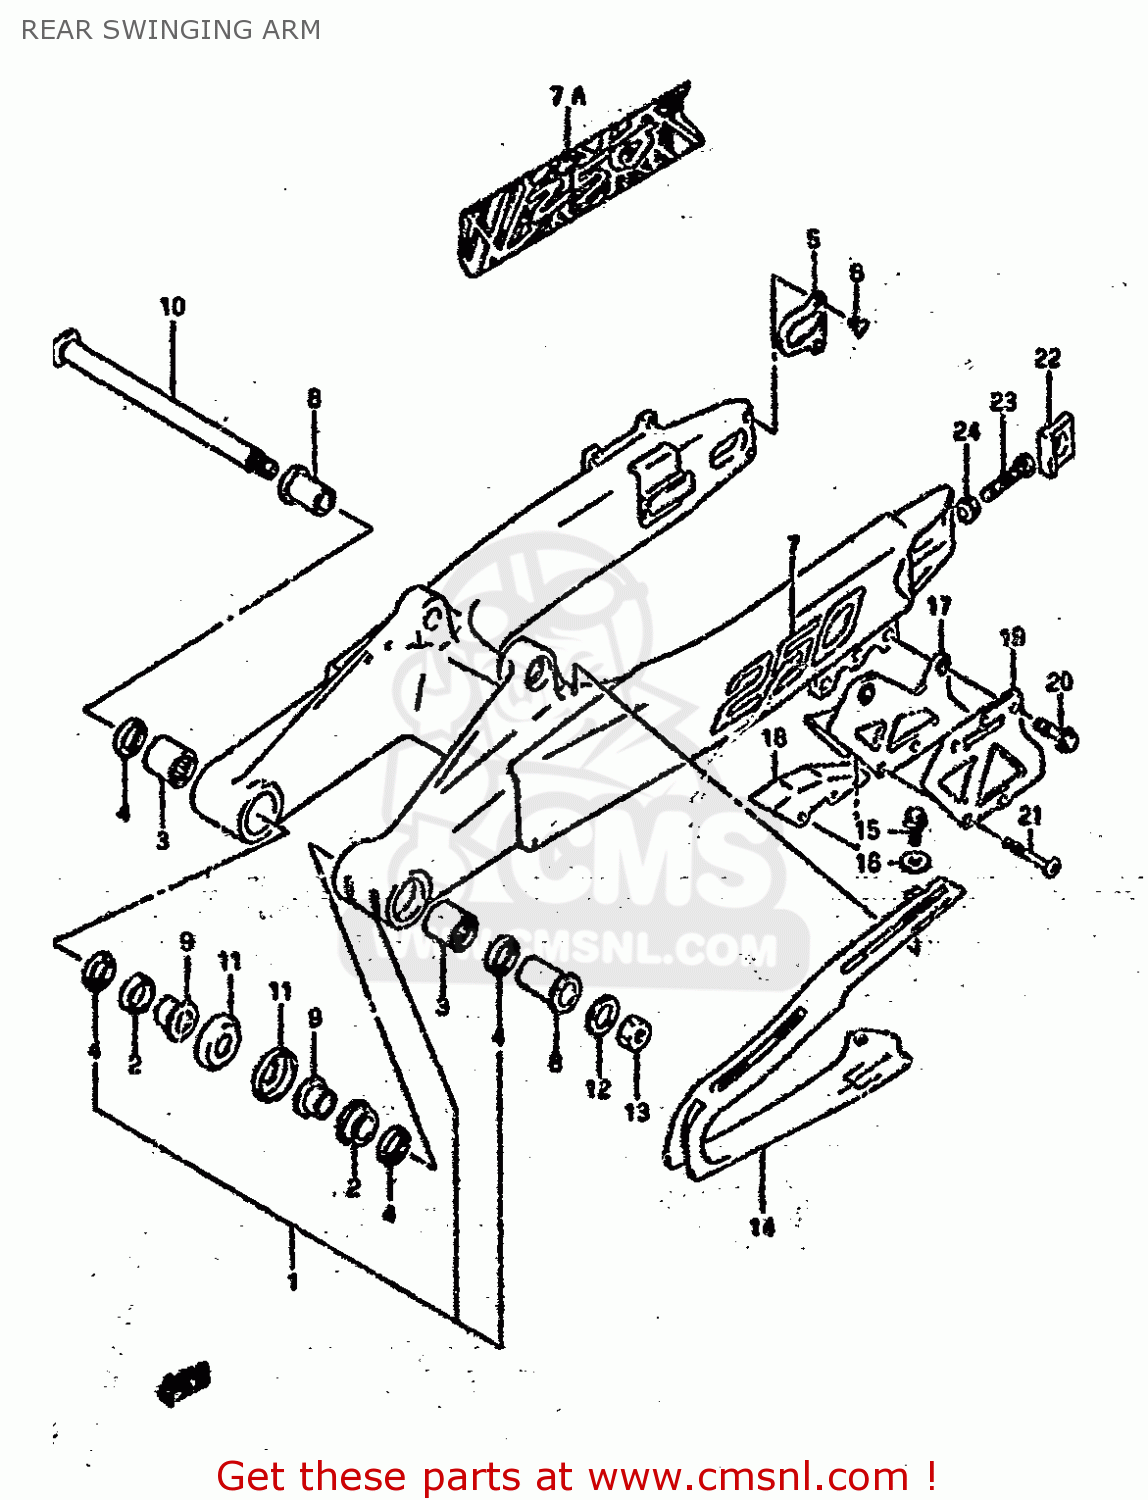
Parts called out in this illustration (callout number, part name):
1	SWING ARM ASSEMBLY,REAR
2	BUSHING,SWGARM PIVOT
3	BEARING(22X29X30)
4	SEAL,OIL(22X29X4)
5	PLATE,SWING ARM,REAR
6	SCREW(5X8)
7	EMBLEM,SWINGINGARM
7A	EMBLEM,SWING ARM
8	SPACER,RR SWGARM PIVOT
9	SPACER,SWGARM PIVOT INNER
10	SHAFT,RR SWINGINGARM PIVOT
11	COVER,SWINGINGARM PIVOT
12	WASHER
13	NUT
14	BUFFER,CHAIN TOUCH DEFENSE
15	BOLT
16	WASHER
17	GUIDE,CHAIN
18	DEFENSE,CHAIN GUIDE
19	PLATE,CHAIN GUIDE OUTER
20	BOLT
21	SCREW(6X40)
22	WASHER,CHAIN ADJUSTER
23	BOLT(8X50)
24	NUT
